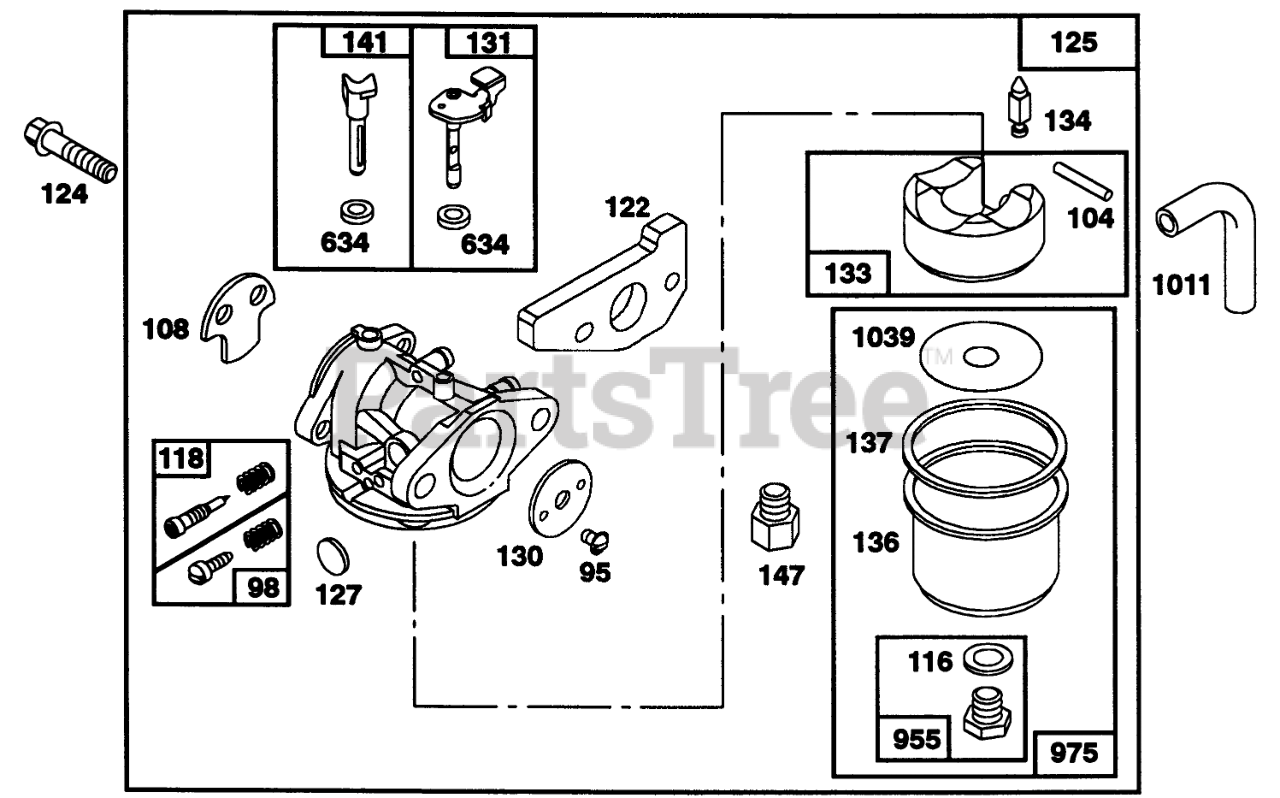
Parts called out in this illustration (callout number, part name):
95	SCREW - ROUND HEAD
98	IDLE ADJUSTING SCREW
104	FLOAT HINGE PIN
108	CHOKE VALVE
116	SEALING GASKET
118	VALVE KIT - NEEDLE
122	ADAPTER ASSEMBLY
124	HEX HEAD SCREW
125	CARBURETOR ASSEMBLY
127	PLUG
130	THROTTLE VALVE
131	THROTTLE SHAFT
133	FLOAT-CARBURETOR
134	Valve-Inlet (Includes Seat)
136	FLOAT BOWL
137	FLOAT BOWL GASKET
141	CHOKE SHAFT
147	JET ADAPTER
634	SEAL WASHER
955	HEX HEAD SCREW
975	CARBURETOR BOWL ASM
1011	VENT TUBE
1039	FLOAT LIMITER
